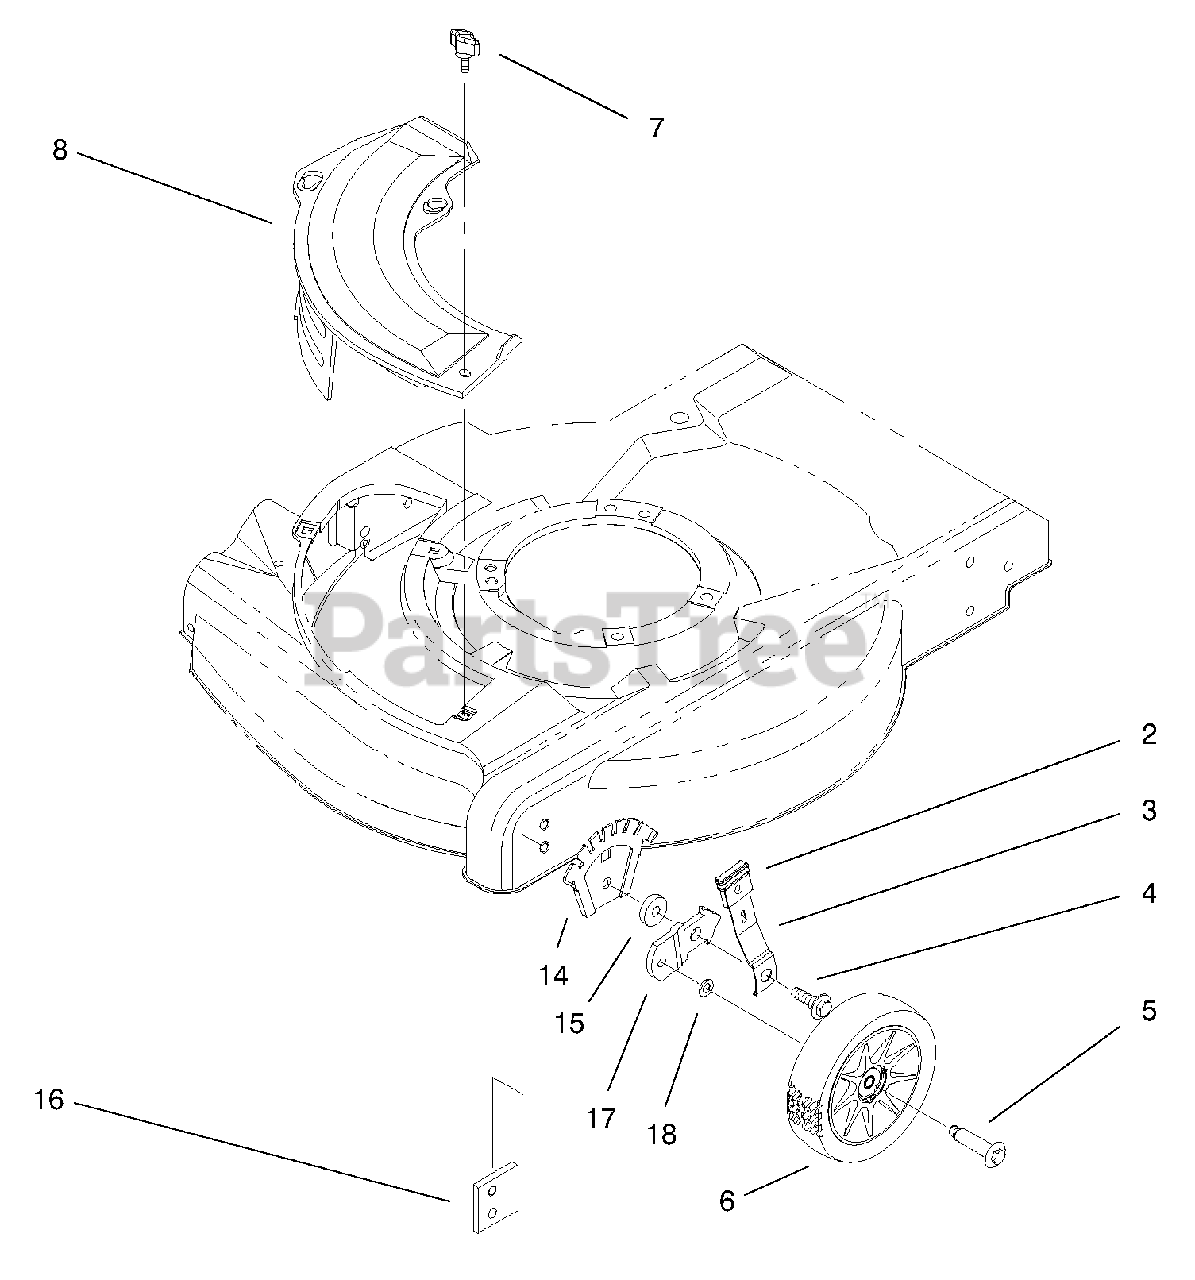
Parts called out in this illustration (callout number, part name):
2	Knob-Lever, Height Adjustment
3	Arm-Front Spring
4	Bolt-Shoulder
5	Bolt-Shoulder
6	Wheel & Tire ASM
8	Plate-Mulch
14	Plate-Height Adjustment
15	Washer-Wheel
16	Plate-Baffle
17	Bracket-Wheel Height Adjustment
